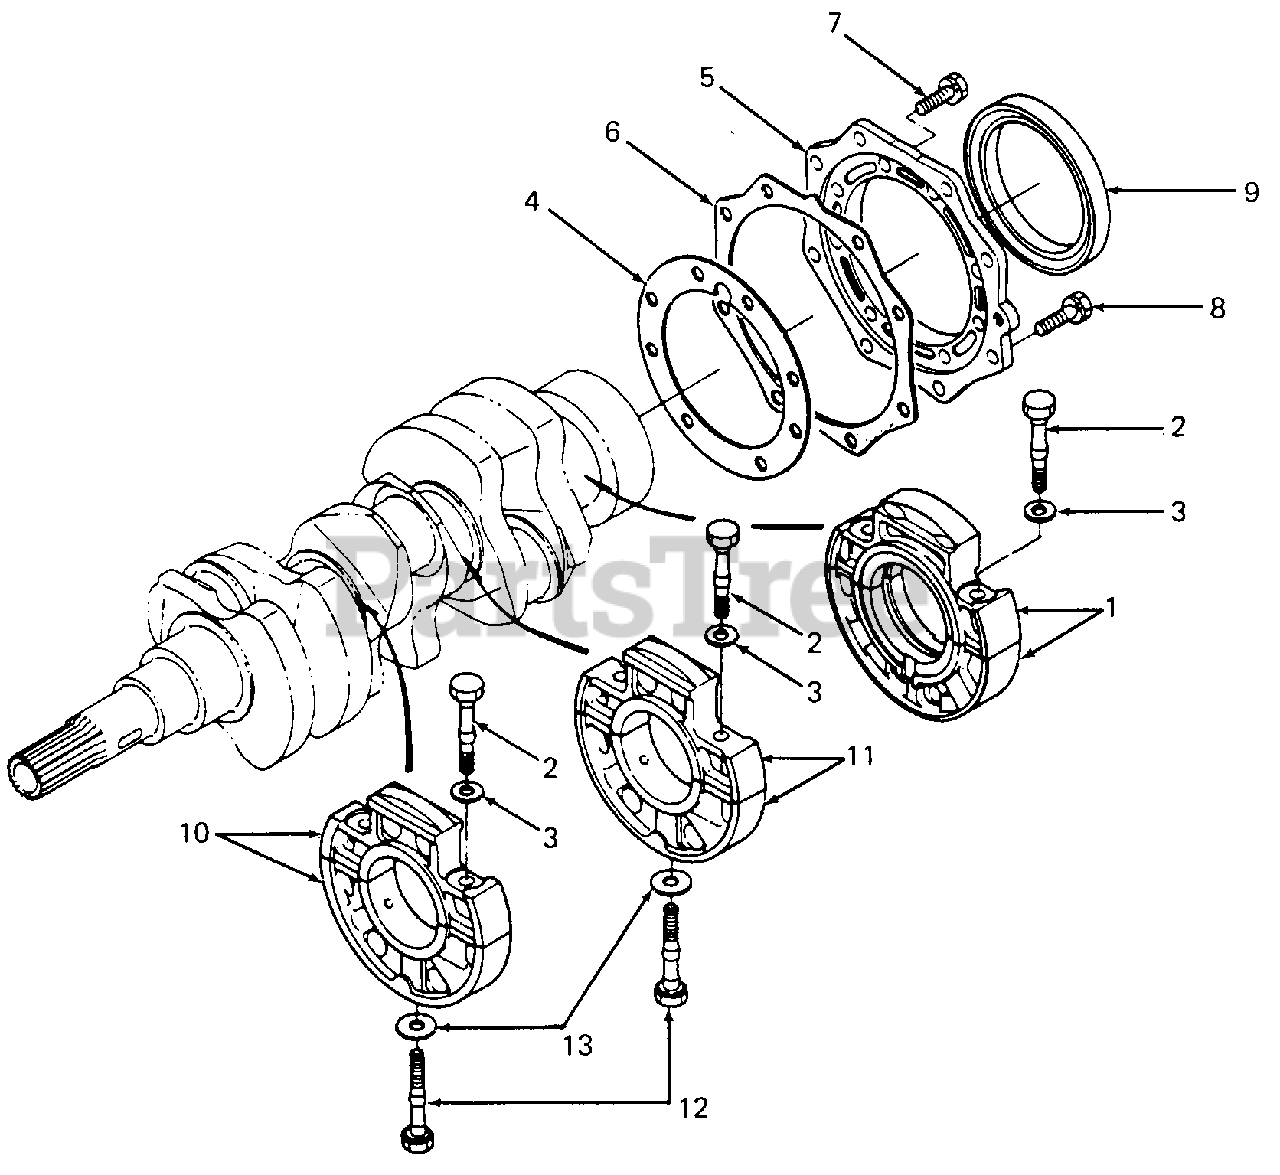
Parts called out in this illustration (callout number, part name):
1	Case, Main Bearing
2	Bolt, Bearing Case
3	Washer, Bearing Case
4	Shim, Bearing Case
5	Cover, Bearing Case
6	Gasket, Bearing Case
7	Screw, Hex Cap w/Washer
8	Screw, Hex Cap
10	Case, Main Bearing - 1
11	Case, Main Bearing - 2
12	Bolt, Bearing Case
13	Washer, Bearing Case
